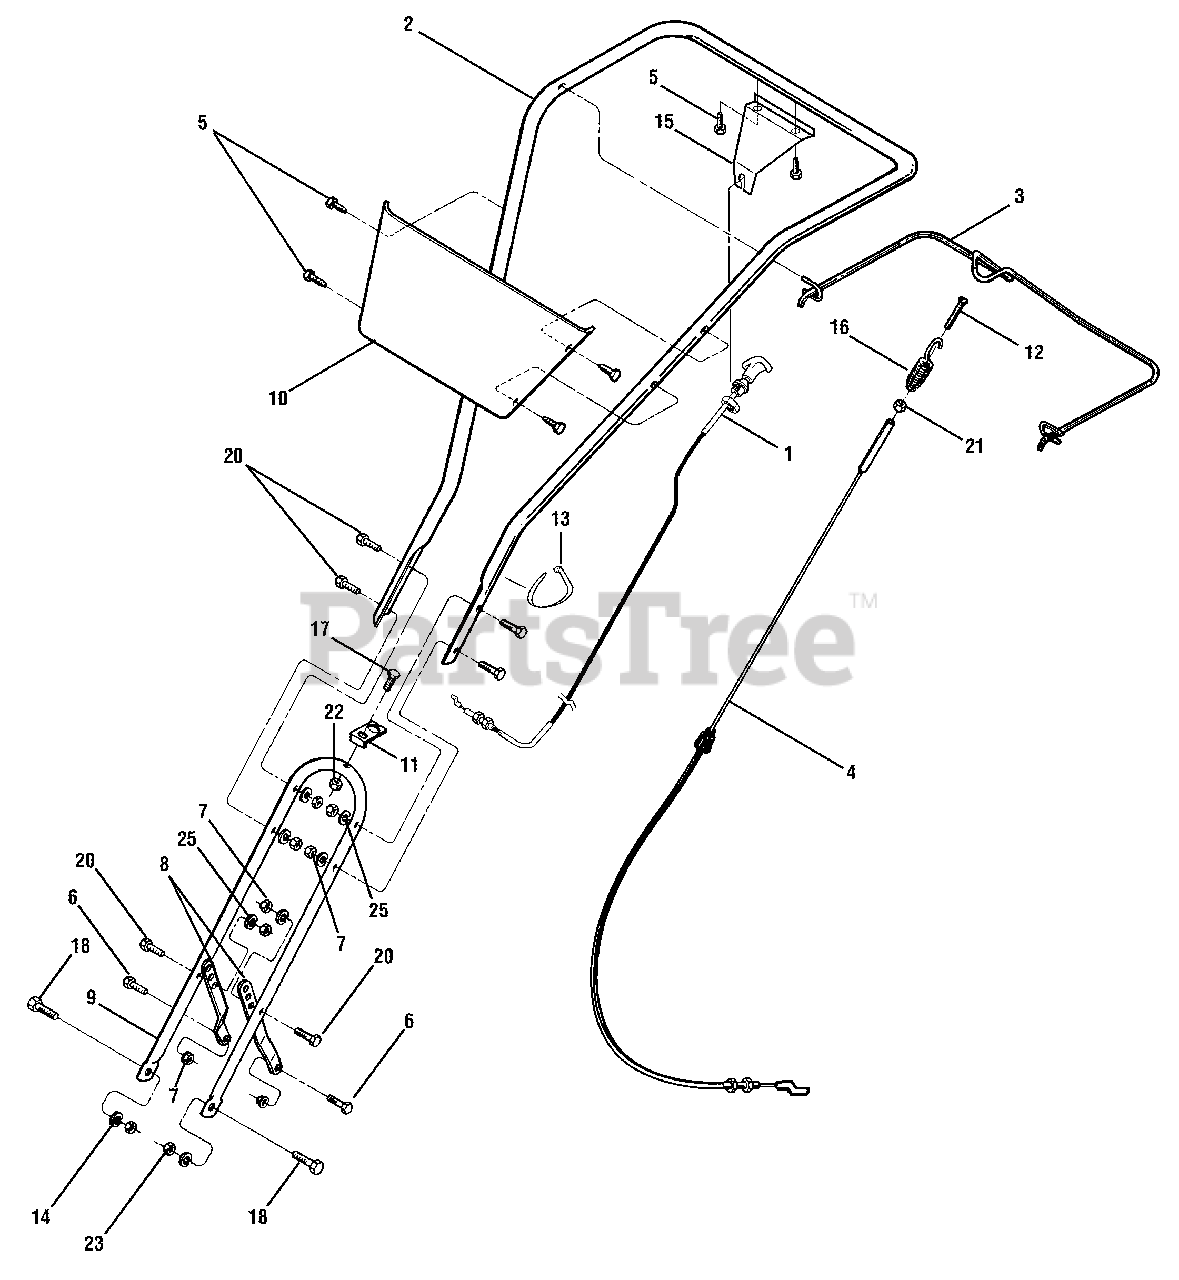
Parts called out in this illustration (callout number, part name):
1	Cable Assembly, Reverse Clutch
2	Upper Handlebar
3	Bail, Forward Clutch
4	Cable Assembly, Forward Clutch
5	Screw, Self-Tapping,1/4-20 x 1/2
6	Screw, Hex, 5/16-18 x 3/4
7	Hex Lock Nut, 5/16-18
8	Handlebar Support
9	Lower Handlebar
10	Panel
11	Tab, Conduit Mount
12	Screw, #10-24 x 2
13	Cable Tie
14	Flat Washer, 3/8
15	Bracket, Reverse Clutch Cable
16	Spring, Forward Clutch
17	Hex Hd. Screw, 1/4-20 x 1-1/4
18	Screw, Hex, 3/8-16 x 3/4
20	Screw, Hex, 5/16-18 x 1-1/2
21	Hex Nut, #10-24
22	Hex Lock Nut, 1/4-20
23	Hex Nut, 3/8-16
25	Lock Washer, 5/16
